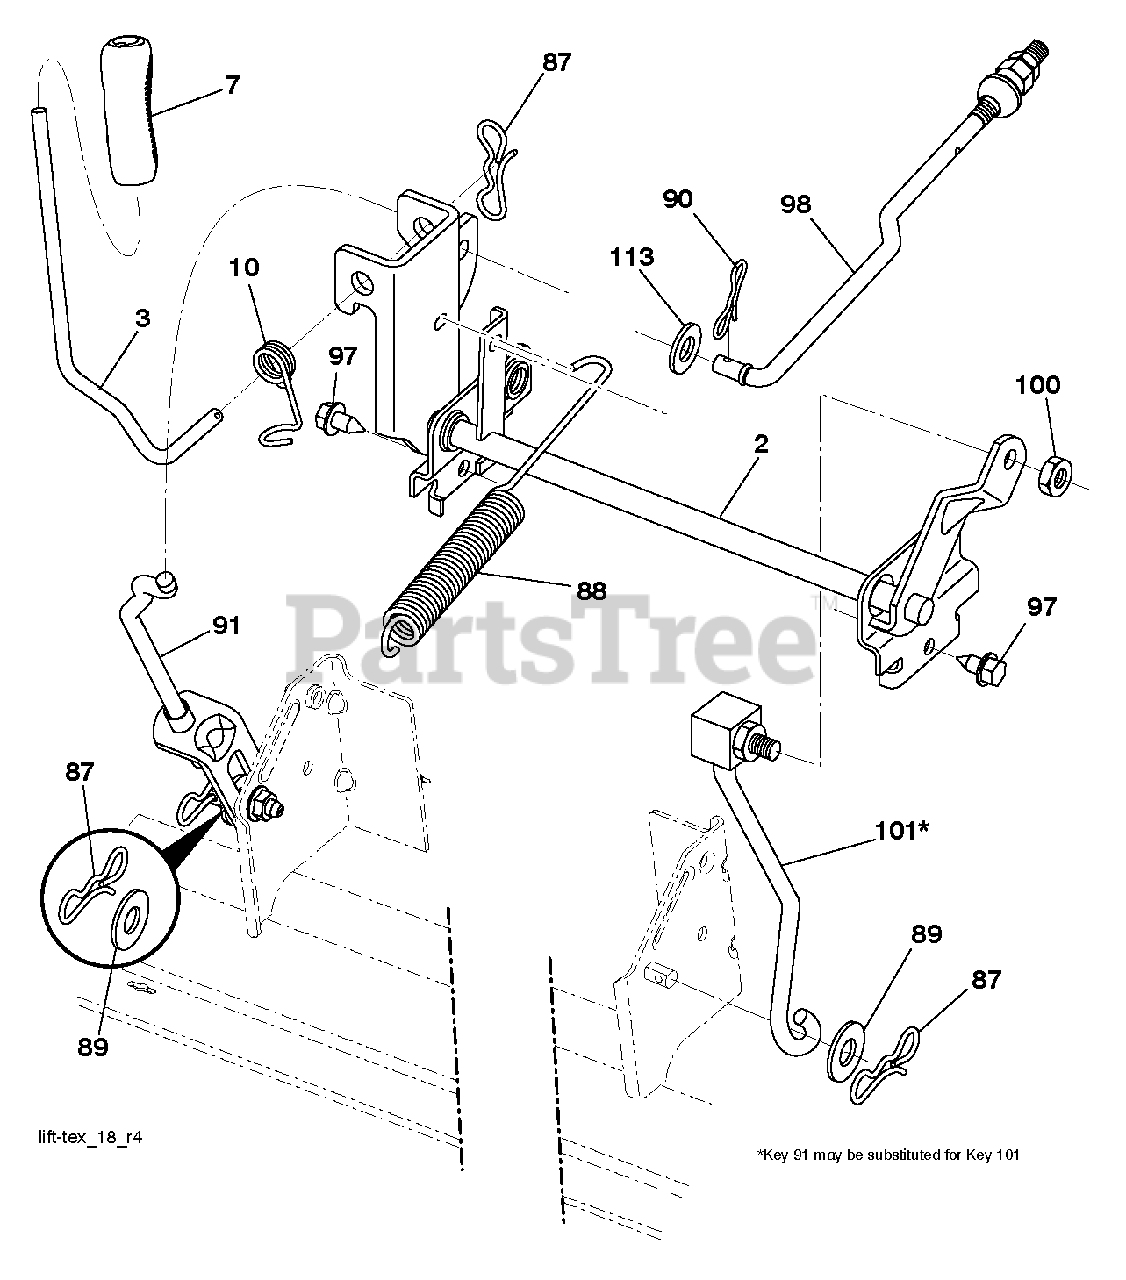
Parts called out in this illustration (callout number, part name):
2	SHAFT.ASM.CROSS.LIFT
3	LEVER.LIFT.HANDLE.LT
7	GRIP, LEVER
10	SPRING.TORSION.LIFT.HA
87	PIN.COTTER.7/16.BOW TI
88	SRPING.LIFT.ASSIST
89	WASHER.CLEAR.ZINC
90	PIN.COTTER.5/16.BOW TI
91	LINK.ASM.LIFT.REAR
97	SCREW, 3/8-16X3/4
98	LINK.ASM.SUSP.FRONT.MWR.10.5
101	LINK.ASM.LIFT.FIXE.38/42/46"
